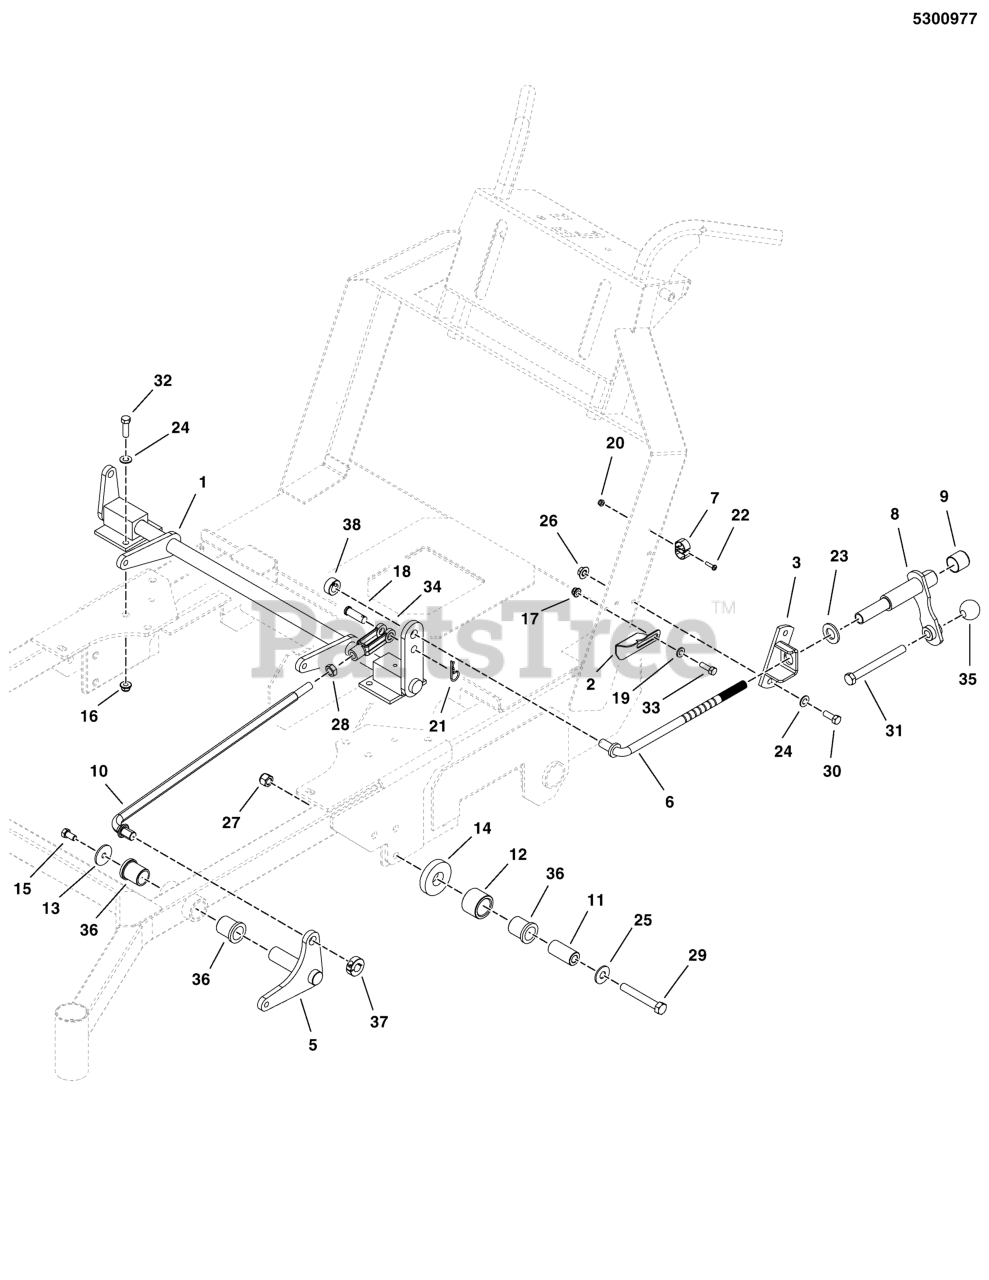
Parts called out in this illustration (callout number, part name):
1	WELD, SHAFT, DECK LIFT, REAR - RED
2	PLATE, DECK HEIGHT - CCW-48 - RED
3	WELD, DECK LIFT, REAR - RED
5	WELD, DECK LIFT LEVER, LH - RED
6	ROD, DECK LIFT, CCW
7	CLIP, SPRING, SW30
8	DECK CRANK, SW30 - BLK
9	CAP, VINYL, 1.062 X 1.00 BLK
10	ROD, LINK, DECK LIFT, FRONT
11	SPACER, .52 X 1.00 X 2.09 - SS
12	ROLLER, DECK HEIGHT
13	WASHER, .390 X 1.50 X .109, YZ
14	WASHER, FRICTION
15	BOLT, 3/8-16 X 3/4, PLT W/PATCH
16	NUT, 3/8-16 HEX NYLOCK FLANGE
17	NUT, 5/16-18 HEX NYLOCK FLANGE
18	PIN, CLEVIS, 1/2 X 1 1/2, YZP
19	WASHER, 5/16 GD.9 FLAT
20	NUT, #10-24 HEX NYLON LOCK
21	PIN, HAIR, .0915 X 1-7/8
22	SCREW, #10-24 X 3/4 ROUND PHILLIPS
23	WASHER, 3/4 SAE
24	WASHER, 3/8 SAE
25	WASHER, 1/2 USS
26	NUT, 3/8-16 HEX SERRATED FLANGE
27	NUT, Hex, Nylon Lock, 1/2-20
28	NUT, 1/2-20 HEX JAM
29	BOLT, 1/2-20 X 3-1/2 GD8 YZ
30	BOLT, 3/8-16 X 1" GD5 CZ
31	BOLT-1/2-13 X 5 GD5 YZ
32	BOLT, 3/8-16 X 1-1/4" GD5 CZ
33	BOLT, 5/16-18 X 1 GD5 YZ
34	CLEVIS, 1/2-20, STEEL, CLEAR ZINC
35	KNOB, PLASTIC, 1/2-13
36	BUSHING, FLANGE
37	COLLAR, 5/8 SPLIT
38	COLLAR, 5/8 SET
